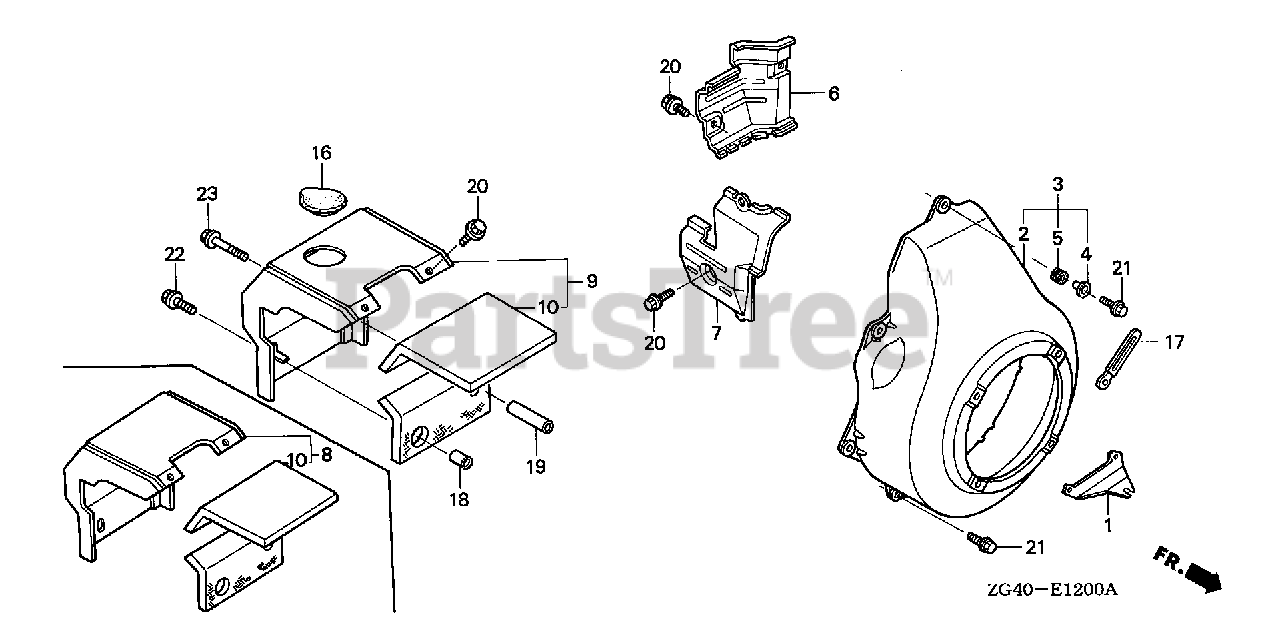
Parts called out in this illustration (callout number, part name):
2	COVER, FAN *NH116M* (URBAN SILVER METALLIC)
6	SHROUD (A)
7	SHROUD (B)
20	BOLT, FLANGE (6X12)
21	BOLT, FLANGE (6X12)
